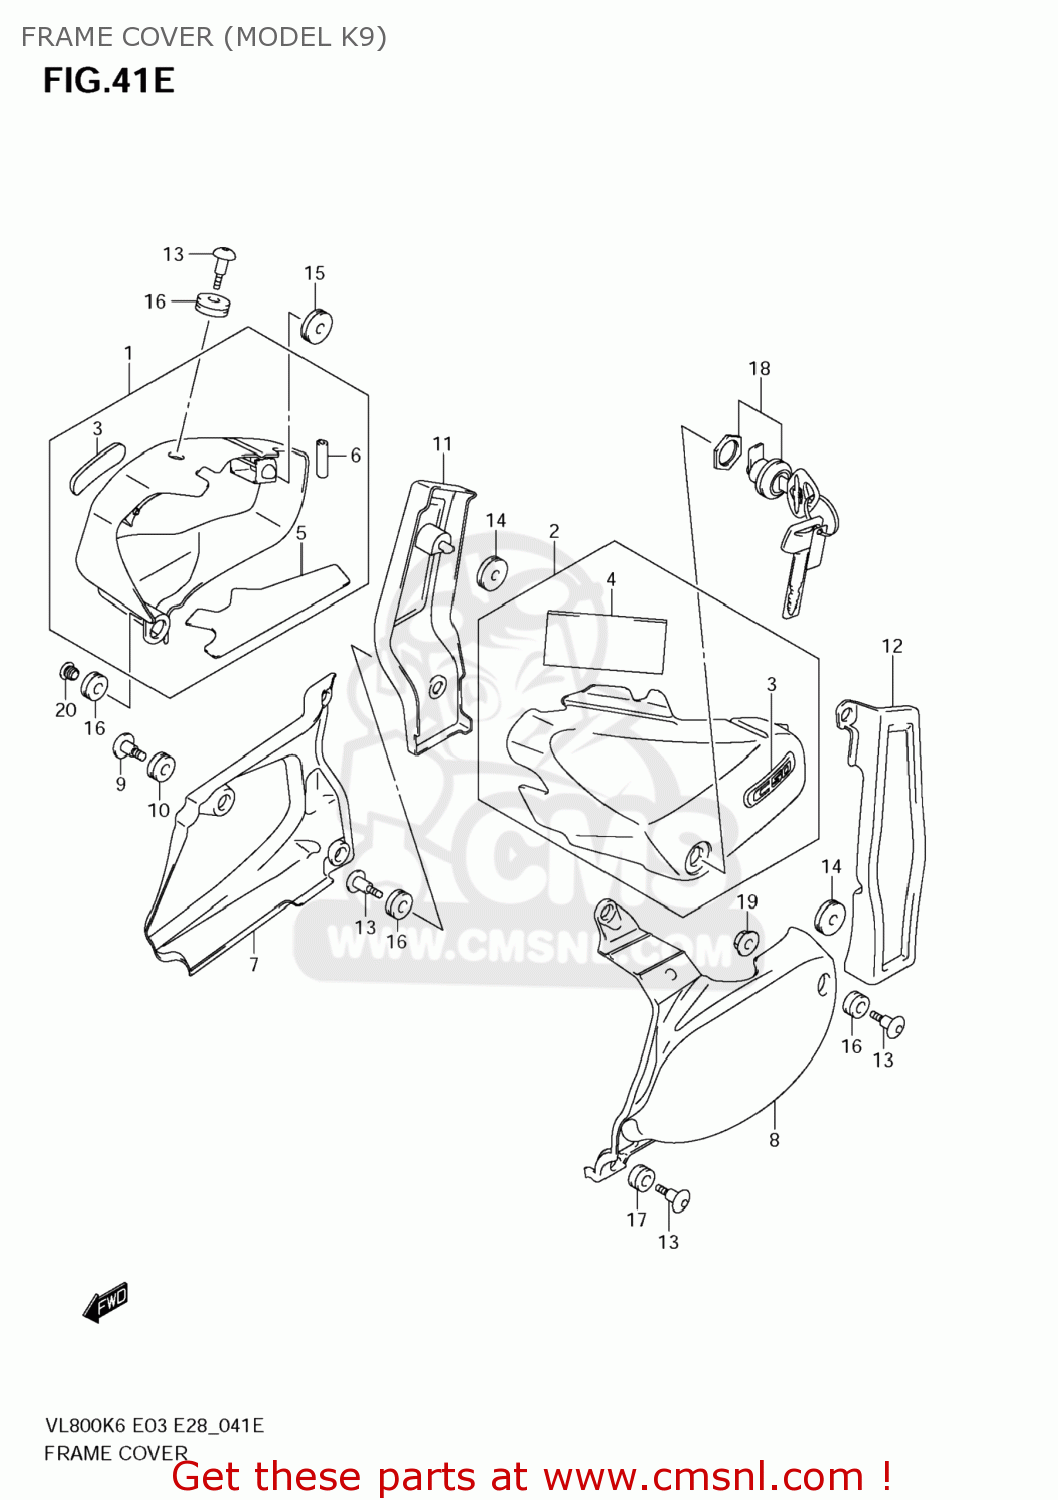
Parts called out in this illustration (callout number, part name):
1	COVER COMP,SIDE
2	COVER,SIDE,L(BLACK)
3	EMBLEM,C50
4	CUSHION,LUGGAGE BOX
5	SHIELD,FRAME COVER
6	MOLDING
7	COVER,SIDE LWR,R
8	COVER,SIDE LWR,L
9	SCREW,SIDE COVER LWR,R
10	CUSHION
11	COVER,SIDE RR,R
12	COVER,SIDE RR,L
13	SCREW(6X20)
14	CUSHION
15	CUSHION
16	CUSHION
17	CUSHION
18	LOCK SET,COVER
19	NUT
20	CAP(OD:14)
